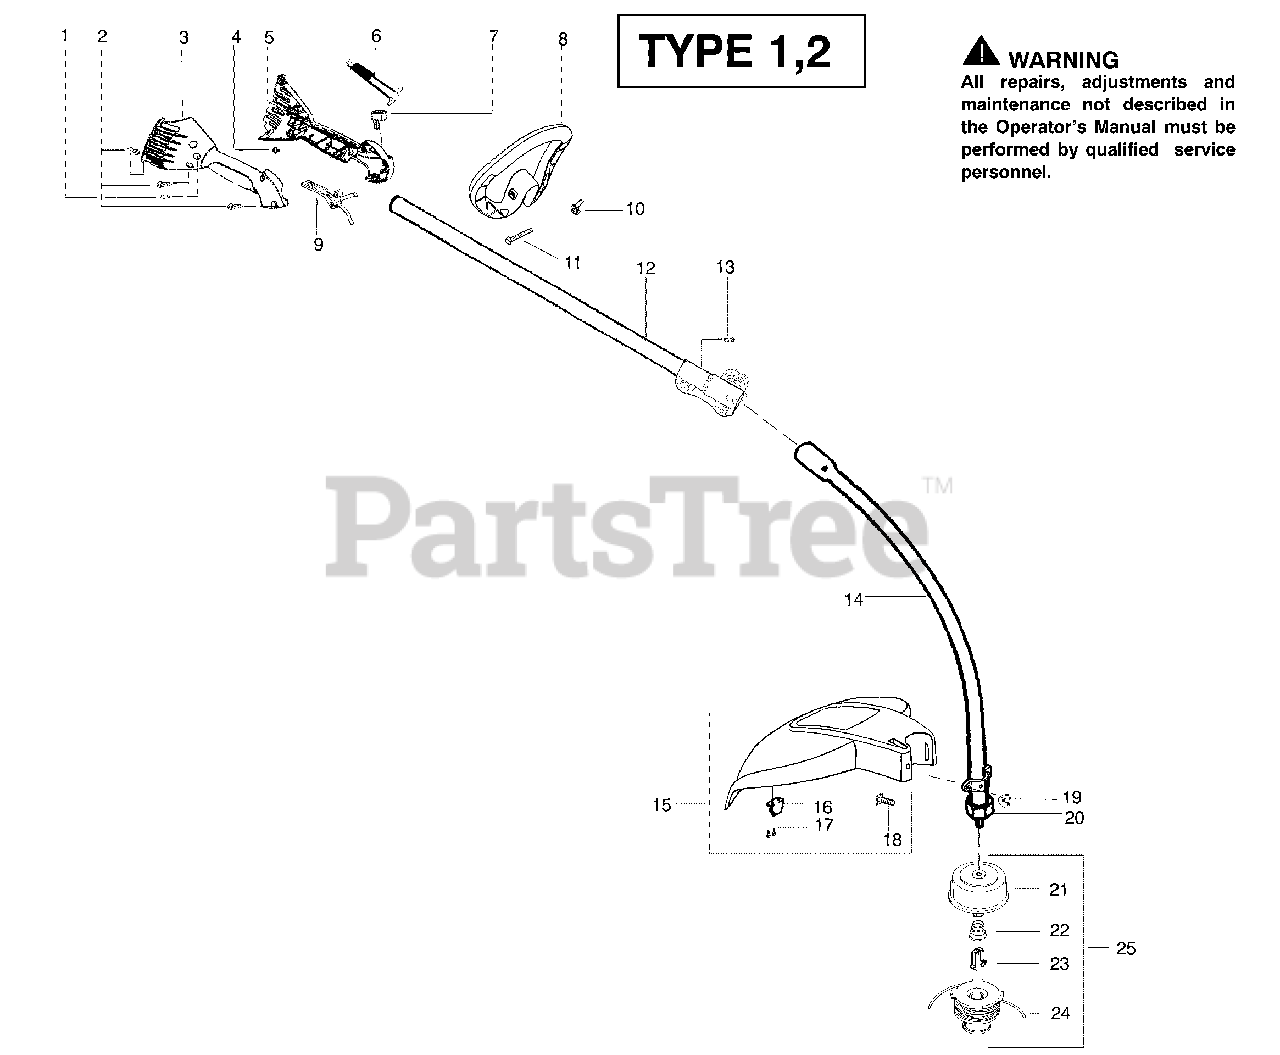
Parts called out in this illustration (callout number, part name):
1	Screw-alignment
3	Hsg.-Throttle right
4	Screw-Cable Retention
5	Hsg.-Left throttle
6	Assy-Wire
7	Kit-Switch
8	Assy-Assist Handle
9	Trigger-Throttle
10	Wingnut
12	Kit-Upper Shaft
14	Kit-Lower Shaft
15	Kit-Shield Assy.
16	Limiter-Line
19	Wingnut
21	Assy-Hub/Arbor
22	Spring-Return
23	Retainer-Spool
24	Accy-Wound Spool
25	Accy-Cutting Head
